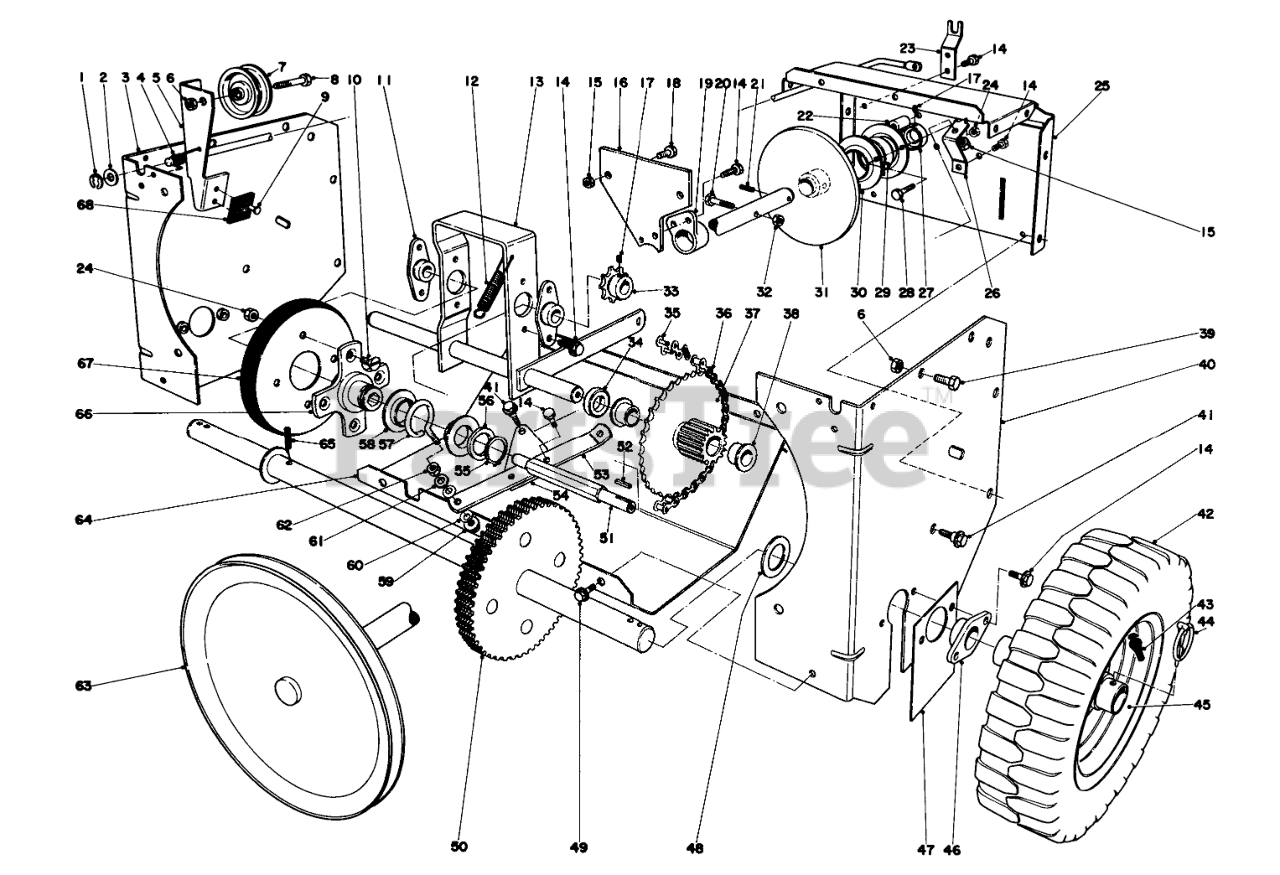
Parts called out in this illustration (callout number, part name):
1	Klip Ring
2	WASHER-FLAT
3	RH TRACT SIDE PLT R
4	TORSION CLUTCH SPRING
5	Clutch Rod (Incl. Ref. #9 & 68)
6	NUT-HEX
7	PULLEY-IDLER
8	SCREW-HH
9	.185 DIA X .375 RT +
10	Screw Flat Head
11	BEARING-WHEEL, FRICTION
12	TENSION SPRING
13	PIVOT SHAFT WA B
14	SCREW-HWHTF
15	NUT-LOCK, CONE
16	SHAFT SUPP BRACKET
17	SCREW-HSH
18	SCREW-HH
19	Bearing-Drive Shaft
20	SCREW-HH
21	PIN-ROLL, SLOTTED
22	DRIVE SET BRC SPACER
23	CLUTCH ROD SUPPORT
24	Nut
25	Center Frame
26	PIVOT BRACKET
27	EXT LOCKING COLLAR
28	SCREW-HH
29	BALL BRG W/COLLAR
30	BRG FLANGE
31	FRICTION PLT WA
32	NUT-LOCK, CONE
33	SPROCKET
34	COSHAFT SPACER
35	LINK-CONNECTING
36	ROLLER-CHAIN
37	Gear & Bushing (Inc. Ref. #38)
38	BUSHING
39	SCREW-HH
40	LH TRACT SIDE PLT R
41	SHOULDER SCREW
42	Tire
43	STEM-VALVE
44	PIN-LYNCH
45	Wheel
46	AXLE BEARING
47	Cover
48	WASHER
49	SCREW-HWH
50	AXLE & GEAR WA
51	FRICTION WHL SHAFT
53	SHIFT LINKAGE
54	PIVOT PLATE
55	RING-RETAINING
56	WASHER-THRUST
57	SLIDER RING COLLAR
58	SLIDER RING
59	NUT-LOCK, FLANGE
60	WASHER-SPRING
61	WASHER-FLAT
62	Nut
63	Drive Shaft
64	LOWER SHIELD R
65	PIN-ROLL, SLOTTED
66	TRACTION DISC HUB
67	Disc
68	BRAKE PAD
